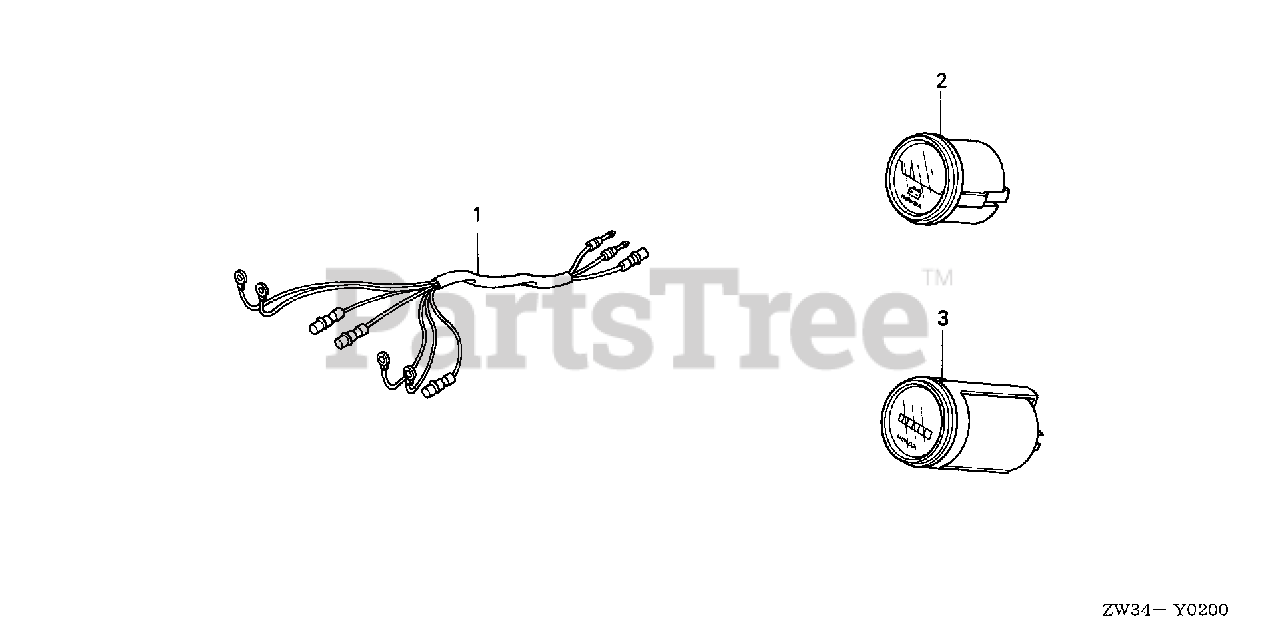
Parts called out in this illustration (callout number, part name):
1	HARNESS ASSY., METER (B)
2	METER ASSY., VOLT (NOT AVAILABLE)
3	METER ASSY., HOUR L.C.D.
